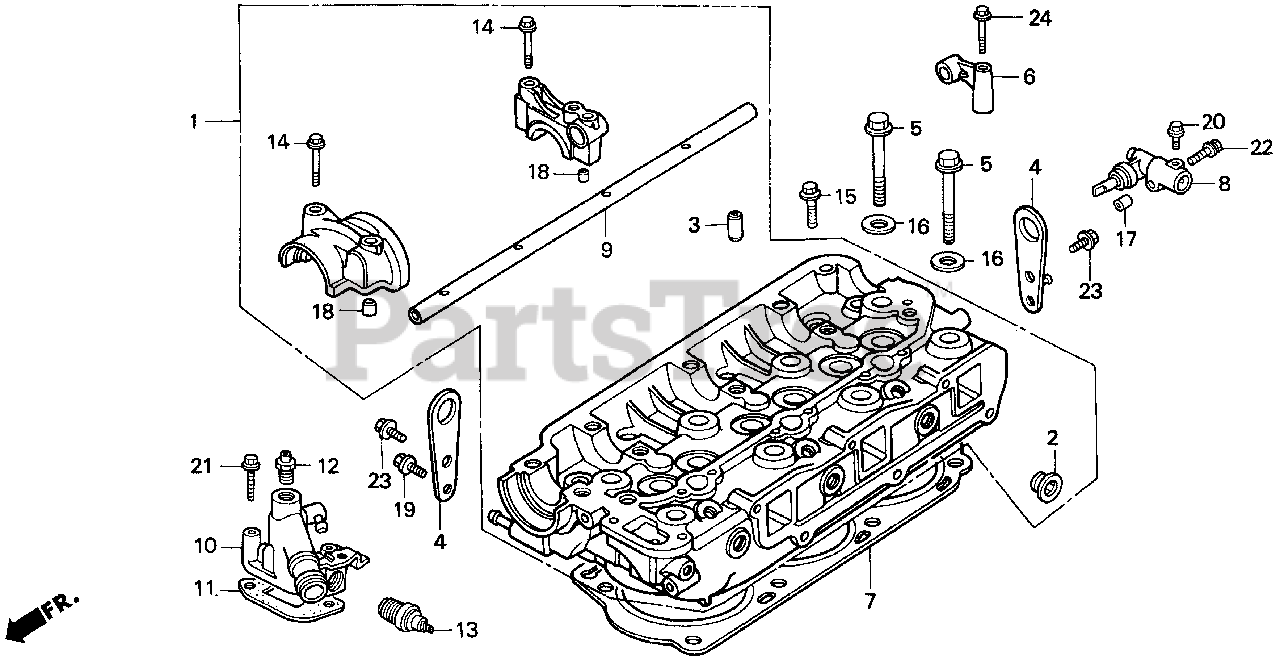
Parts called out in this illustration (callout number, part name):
1	CYLINDER HEAD ASSY.
2	BOLT, SEALING (18MM)
3	GUIDE, VALVE (OS)
4	PLATE, HANGER
5	BOLT, FLANGE (12X96)
6	HOLDER, ROCKER ARM SHAFT
7	GASKET, CYLINDER HEAD (1.25)
7	GASKET, CYLINDER HEAD (1.35)
7	GASKET, CYLINDER HEAD (1.45)
8	CASE ASSY., TACHOMETER GEAR
9	SHAFT, ROCKER ARM
10	JOINT, WATER OUTLET
11	GASKET, WATER OUTLET JOINT (NON-ASBESTOS)
12	BOLT, BREATHING WATER
13	SENDING UNIT, WATER TEMPERATURE (DENSO)
14	BOLT, FLANGE (8X62)
15	BOLT, FLANGE (8X45) (NA USE ALT:90103-KF0-000)
16	WASHER, PLAIN (12MM)
17	PIN A, DOWEL (8X10)
18	PIN A, DOWEL (10X16)
19	BOLT, FLANGE (6X14)
20	BOLT, FLANGE (6X25)
21	BOLT, FLANGE (6X35)
22	BOLT, FLANGE (6X40)
23	BOLT, FLANGE (8X20)
24	BOLT, FLANGE (8X55)
